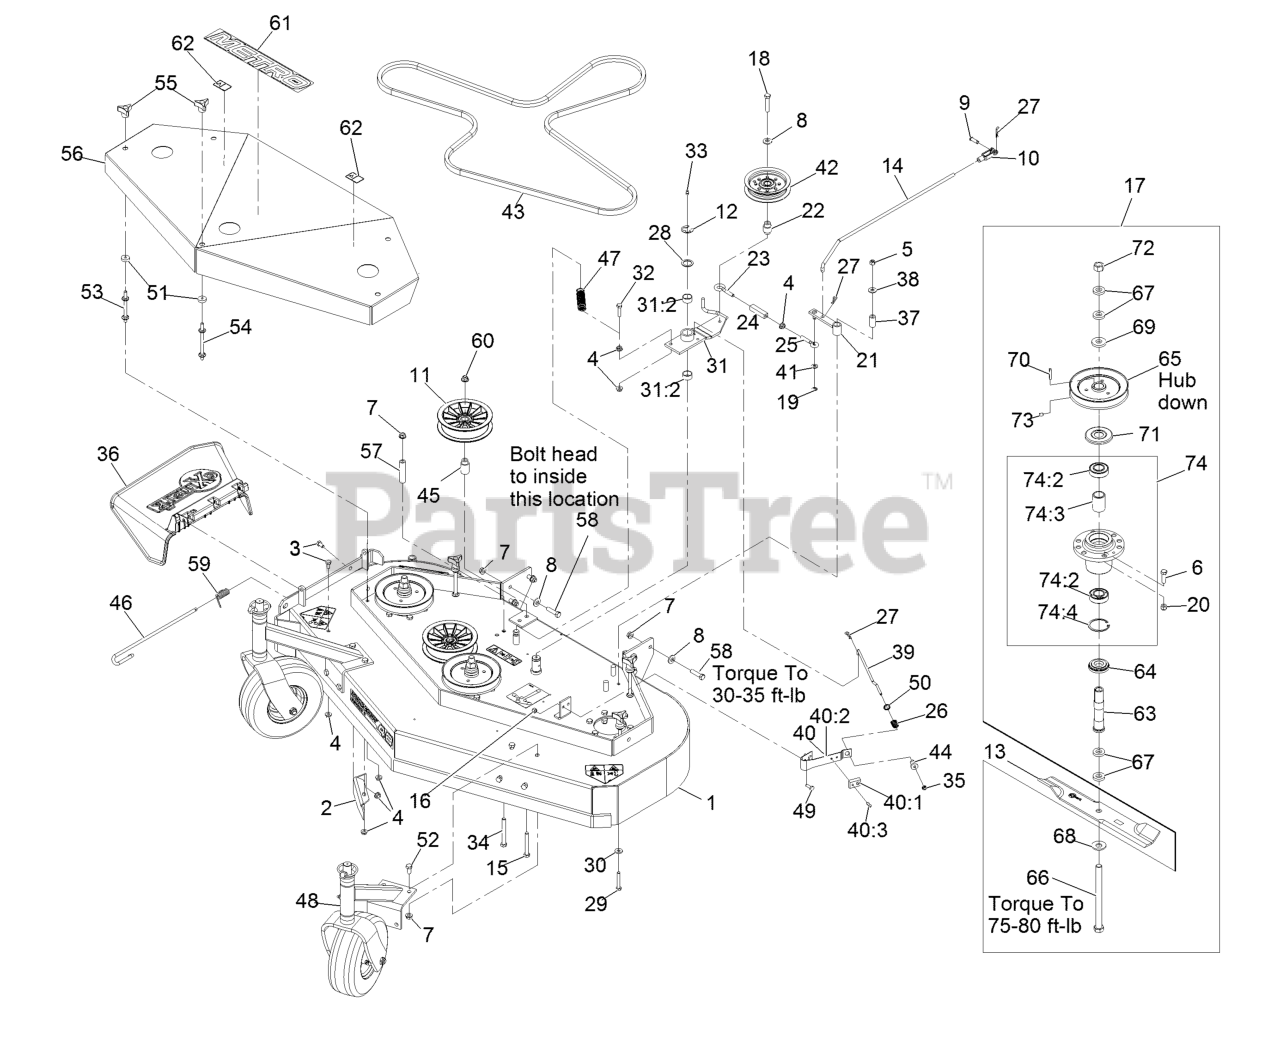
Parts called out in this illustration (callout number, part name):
1	Deck W/Decals And Dogleg
2	Baffle-Dogleg
3	Screw-HH 5/16-18 X 5/8
4	Nut-Whizlock 5/16-18
5	Nut-Nyloc 5/16-18
6	Screw-HH 3/8-16 X 1 1/4
7	Nut-Whizlock 3/8-16
8	Washer-Spring Disc 3/8
9	Pin-Clevis 5/16 X 1 49/64
10	Yoke-Adjustable
11	Pulley,Idler 5"
13	Blade, 16.25 Solid
13	Blade, 16.25 Mulching
13	Blade, 16.25 Notched
13	Blade,Low Lift 16.25
13	Blade-Extreme 2, 16.25"
14	Arm-Assist, Linkage
15	Screw-HH 3/8-16 X 2 3/4
16	Nut-Nyloc 1/4-20
17	Asm, Cutter Housing Complete
18	Screw-HH
20	Nut-Nyloc 3/8-16
21	Arm-Assist, 32/36
22	Bushing-Engagement
23	Eyebolt-Thread, LH
24	Body-Turnbuckle
25	Eyebolt-Thread, RH
26	Spring-Compression
27	Hairpin-Cotter
28	Washer-Spindle
29	Screw-HH 5/16-18 X 2
30	Washer-Spring Disc 5/16
31	Idler Arm ASM
31:2	Sleeve-Bearing
32	Screw,HH Special 5/16-18 X 1.25
33	Zerk-1/4-28 Str
34	Screw-HH 3/8-16 X 3-1/4
35	Nut-Nyloc 1/4-20 Thin
36	Deflector-Discharge
37	Tube-Pivot
38	Washer-5/16 Std
39	Rod-Brake
40	Pad And Spring ASM
40:1	Pad-Brake
40:2	Spring
40:3	Rivet 3/16 X 1/2
41	Washer-5/16 SAE
42	Pulley-Idler
43	Drive Belt (Main Deck) 48"
44	Spacer-Flanged
45	Bushing-Idler
46	Pin-Chute
47	Spring-Extension
48	ASM-Caster Mnt W/Weight
49	Screw-HH 1/4-20 X 3/4
50	Ring-Push On
51	Washer-Belt Shield
52	Screw-HH 3/8-16 X 3/4
53	Stud-Shield, Belt (Short)
54	Stud-Shield, Belt (Long)
55	Knob-3 Prong
56	ASM,Shield W/Decals 48 Metro
58	Screw-HH 3/8-16 X 1 1/2
59	Spring, Torsion
60	Nut-Nyloc 3/8-16 Flg
61	Decal-Metro
62	Decal-Warning
63	Tube-Spindle, Short
64	Spacer-Guard Bottom
66	Screw-Cap, HH
67	Spacer-Blade Drive
68	Washer-Spring Disc 5/8
70	Key-Machine 1/4 X 3/16 X 1 1/4
71	Guard-Bearing Top
72	Nut-Hex 5/8-18
73	Setscrew-5/16-18 X 3/8
74	Cutter Housing ASM
74	Asm, Cutter Housing W/Bearings
74:2	Bearing-Jackshaft
74:3	Spacer-Bearing
74:4	Ring-Retaining
